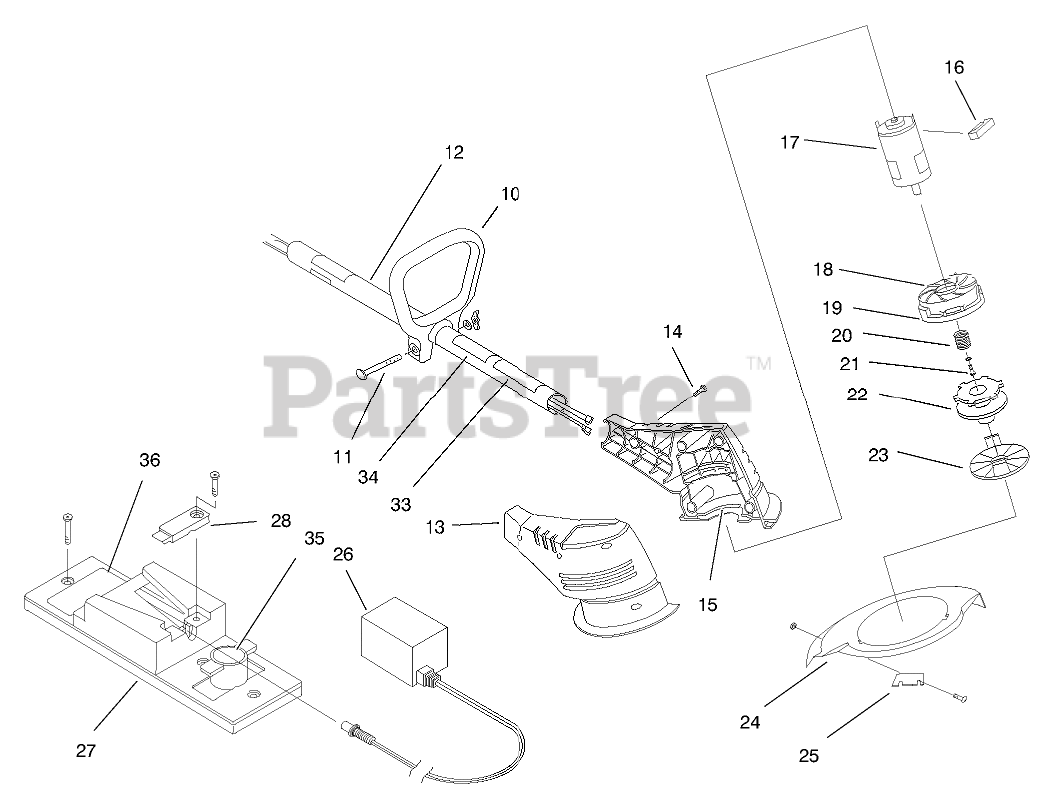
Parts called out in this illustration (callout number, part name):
10	D-HANDLE
11	HARDWARE - D-HANDLE
12	ASSEMBLY - BOOM
13	HOUSING - MOTOR
14	SCREW - HOUSING
15	SUPPORTS - MOTOR (3)
16	BLOCK - ANTI-ROTATION
17	MOTOR
18	Outer Spool and Eyelet (Incl. Ref. #19)
19	EYELET
20	SPRING
21	SCREW & WASHER
22	Inner Reel and .065 Line (15 ft.)
23	COVER - REEL
24	Guard and Blade Assembly (Inc. Ref. #25)
25	ASSEMBLY - BLADE
26	CHARGER - BATTERY
27	ASSEMBLY - WALL STATION
28	WALL STATION CLAMP/SCREW
33	Decal-Safety Symbol
34	DECAL - UL SAFETY WARNING
35	DECAL - TORO LOGO
36	Decal-Caution
